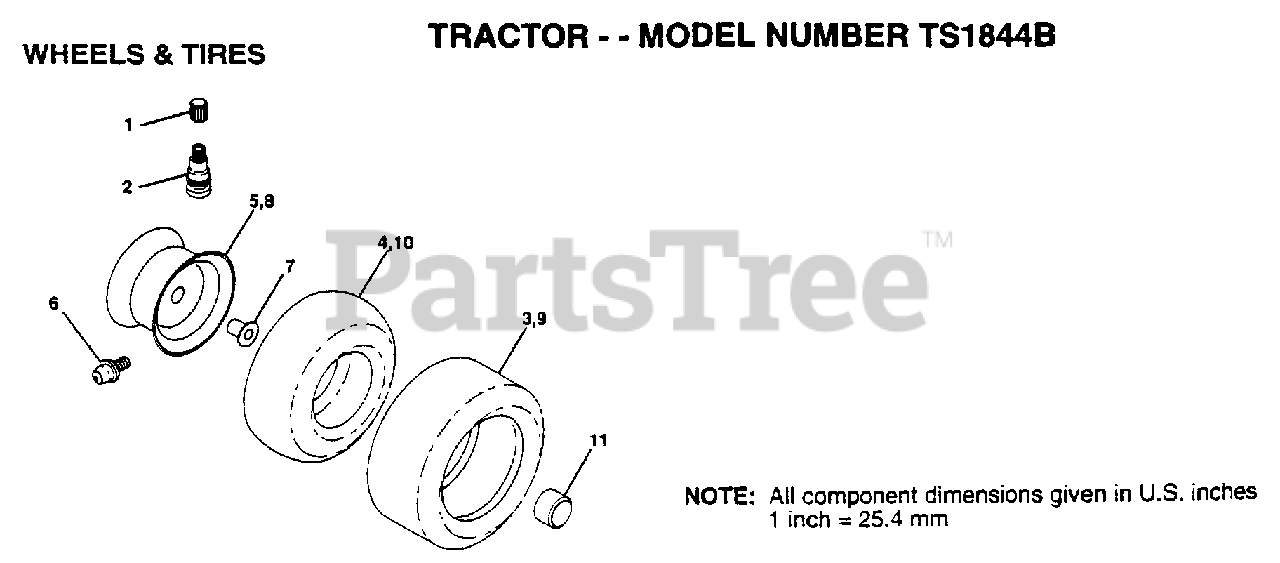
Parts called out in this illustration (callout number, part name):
1	VALVE CAP
2	VALVE STEM LT
4	TUBE.5.3/4.5/6
5	RIM.FRONT.
6	FITTING LT
7	"FLANGE, BEARING"
8	RIM.REAR.417
10	TUBE.23X8/10-12
11	HUB CAP
